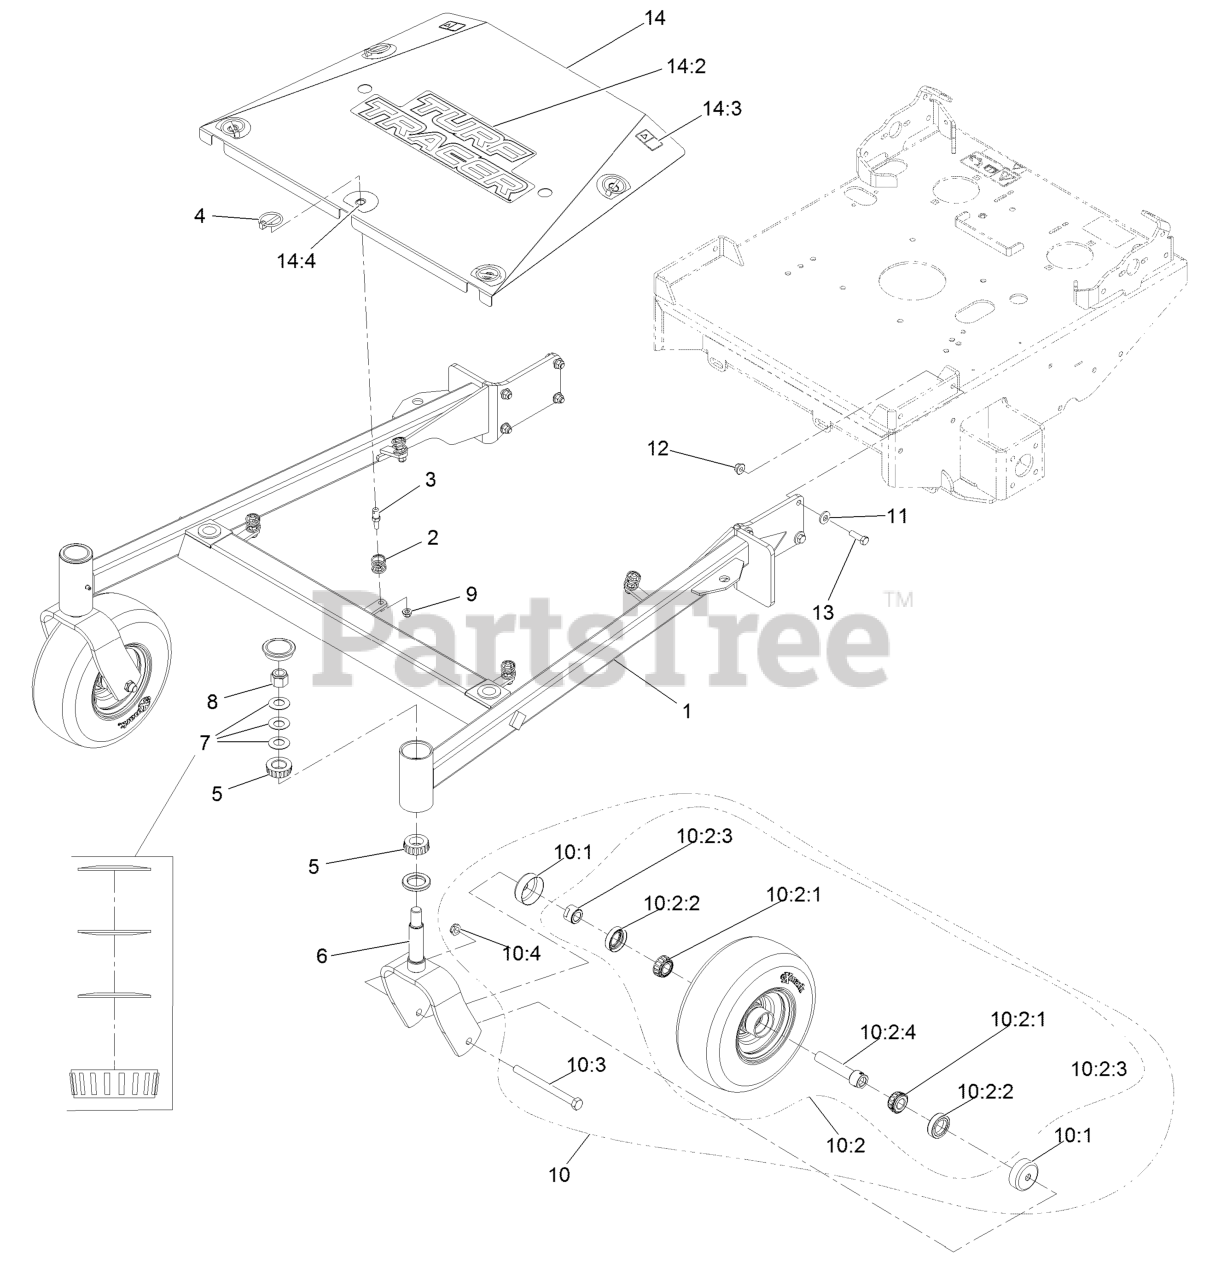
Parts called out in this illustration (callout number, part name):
1	ASM, Front Frame W/ Bearings, 60
3	Pin-Spring
4	Pin-Lynch
5	Cone-Bearing Tapered Roller
6	Wld, Caster Fork
7	Washer-Spring Disc
8	Nut-Nyloc 3/4-10
9	Nut-Nyloc 5/16-18 Flg
10	Asm, Wheel And Bearings
10:1	Guard-Seal
10:2	Wheel And Bearing ASM
10:2:1	Bearing-Cone Tapered Roller
10:2:2	Seal-Double Lip
10:2:3	Spacer-Nut
10:2:4	Caster Axle ASM
10:3	Screw-HH 1/2-13 X 6
10:4	Nut-Nyloc 1/2-13 Thin
11	Washer-Spring Disc 3/8
12	Nut-Nyloc 3/8-16 Flg
13	Screw-HH 3/8-16 X 1 1/4
14	ASM, Center Shield W/Decals, 60
14:2	Decal-Turf Tracer
14:3	Decal-Warning
14:4	Decal-Scratch Cover
